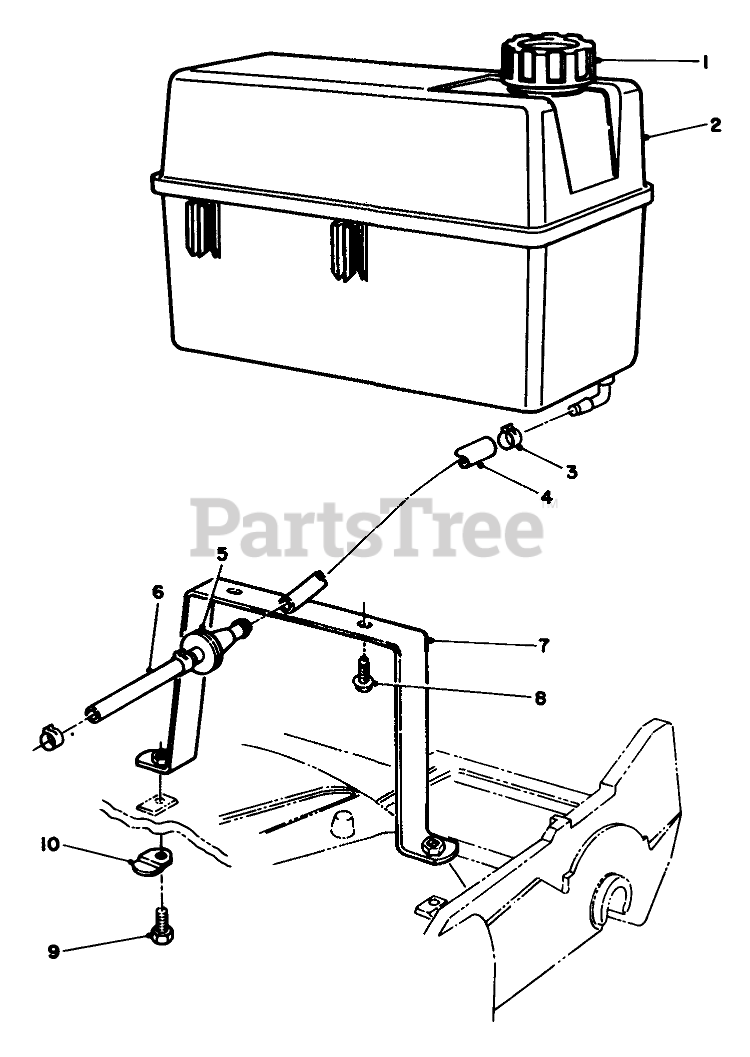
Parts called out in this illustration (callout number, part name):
1	GAS CAP ASM
2	Tank-Gas
3	CLAMP-FUEL LINE
4	HOSE-FUEL
5	FILTER-FUEL
6	HOSE-FUEL
7	Wa-Base
8	SCREW-HWH
9	SCREW-HH
10	SHIELD-RETAINER
